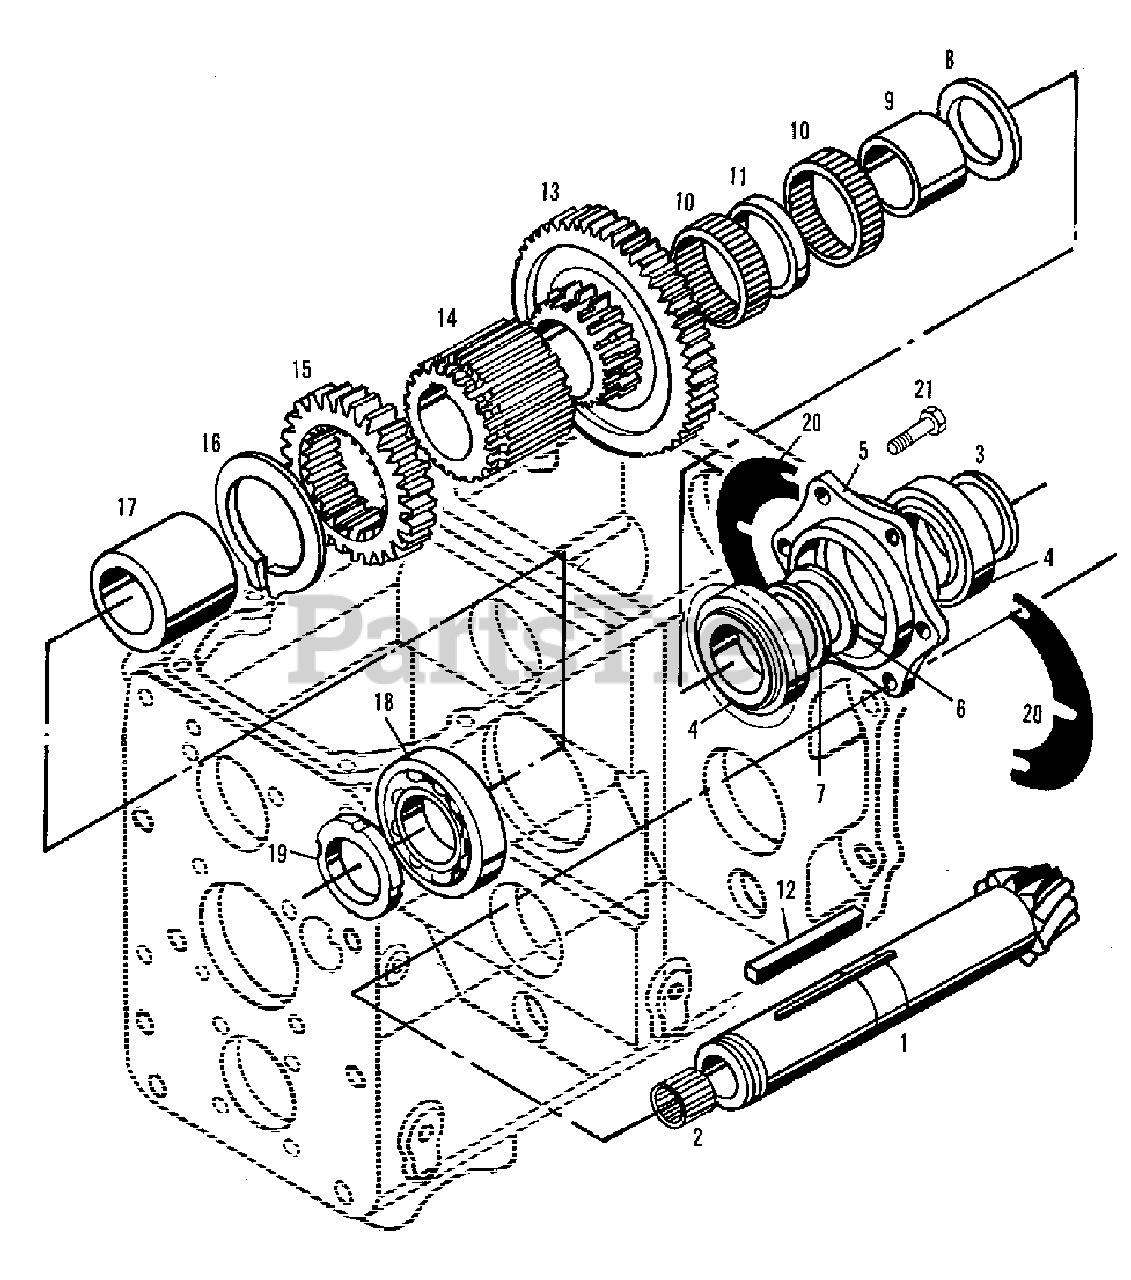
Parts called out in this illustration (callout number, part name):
1	SHAFT, pinion-drive (Not serviced; order 2098001 SHAFT & RIDING GEAR KIT)
2	BEARING, needle
3	WASHER, thrust
4	BEARING, tapered roller
5	CASE, bearing - drive pinion
6	WASHER (0.1)
6	WASHER (0.15)
6	WASHER (0.2) (Select)
6	WASHER (1.0)
7	SPACER, drive pinion
8	WASHER, thrust
9	RING, inner - shell type needle bearing
10	BEARING, needle
11	COLLAR, distance - needle bearing
13	GEAR, lo range
14	COLLAR, hi & lo range
15	GEAR, sliding - hi & lo range
16	RING, M65, snap - external
17	COLLAR, distance
18	BEARING, ball
19	NUT, rolling bearing
20	SHIM (0.1)
20	SHIM (0.2) (Select)
20	SHIM (0.4)
21	CAPSCREW, M8 x 25, w/lockwasher
